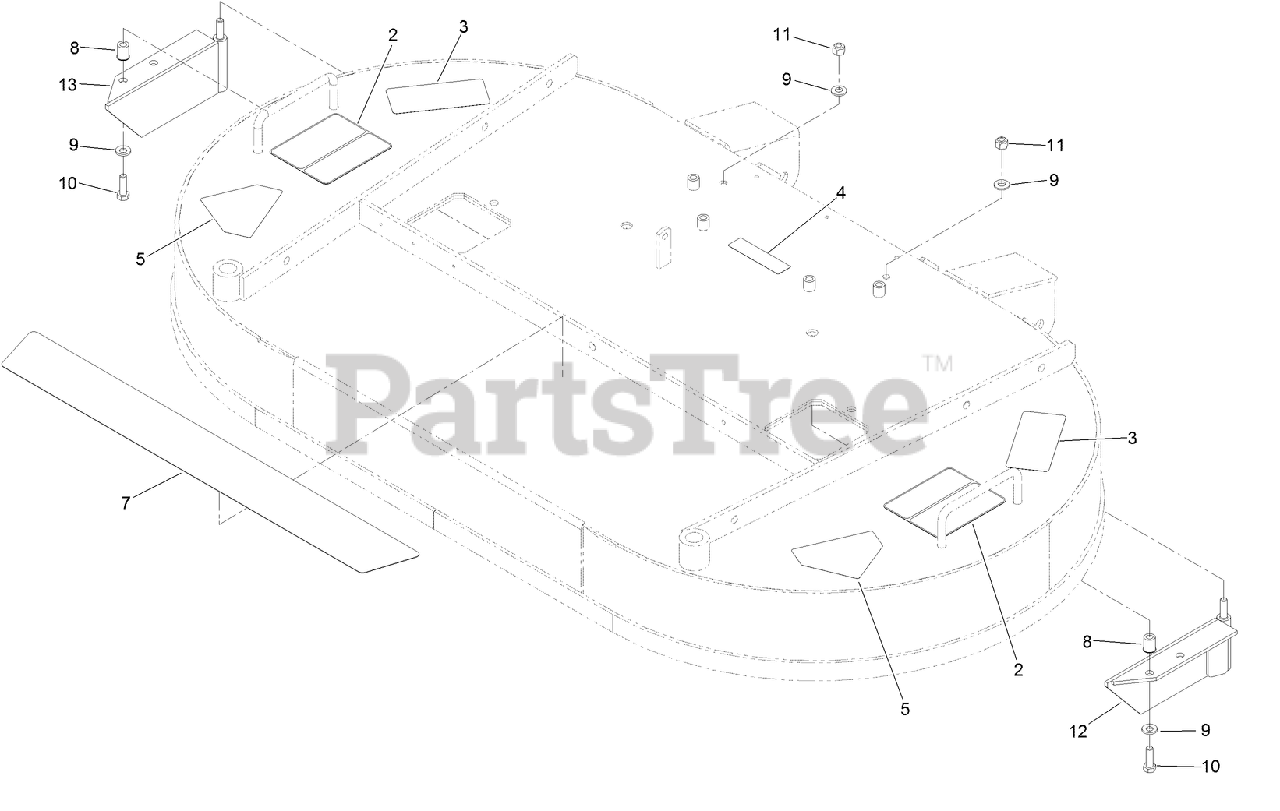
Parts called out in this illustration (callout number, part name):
2	DECAL-CUTTING HEIGHT ADJUSTMENT
3	DECAL-TORQUE
4	DECAL-COVER, MISSING
5	DECAL-DANGER
7	PAD-ANTI SKID
8	NUT-INSERT
9	WASHER-SPRING
10	SCREW-HH
11	NUT-LOCK, NI
12	BAFFLE-LH
13	BAFFLE-RH
